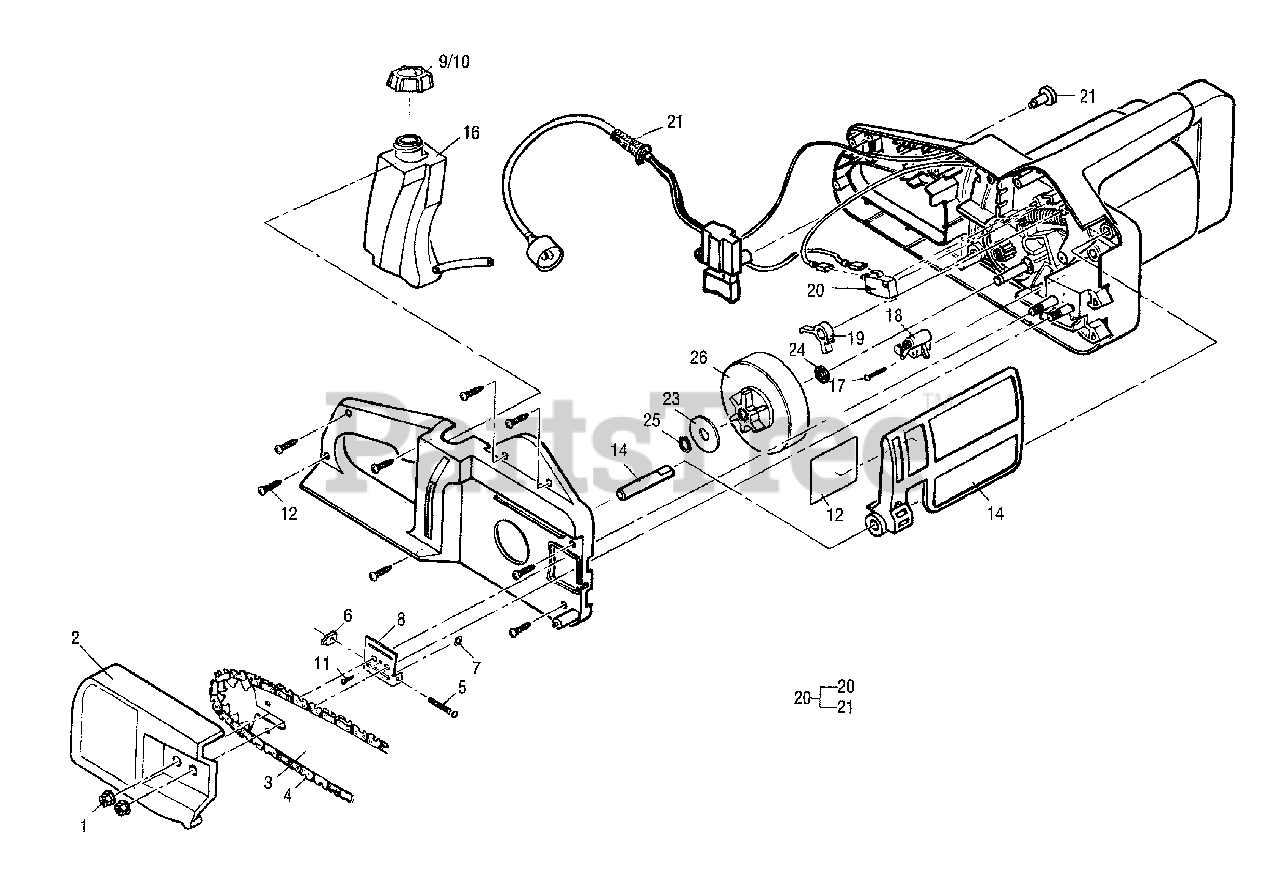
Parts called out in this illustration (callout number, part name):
1	Nut, Bar Retaining Hex 1/4-28
2	Cover, Sprocket with Bushing
3	Bar
4	Chain
5	Elec Bar Adj Screw Nut & Ring
6	Nut, Bar adjust
7	Ring, Retaining
8	Plate, Bar Tension
9	Oil Cap 7/8"
10	Oil Cap 1"
11	Screw #4 x 5/8 Pn Hd
12	Label, Warning
13	Screw, #8 x 3/4 Ph Pan Hd
14	Lever, Axle Brake
15	Lever, Brake
16	Oil Tank / Tubing / Filter Asy
17	Screw, #6 x 3/4 Ph Pan Hd
18	Oil Pump / Tubing Asy
19	Lever, Micro Switch
20	Switch, Micro
21	Kit, Cord and Switch
22	Switch/Button Asy
23	Washer, Sprocket
24	Washer, Flat, Sprocket
25	Ring, Retainer
26	Gear/Sprocket kit
